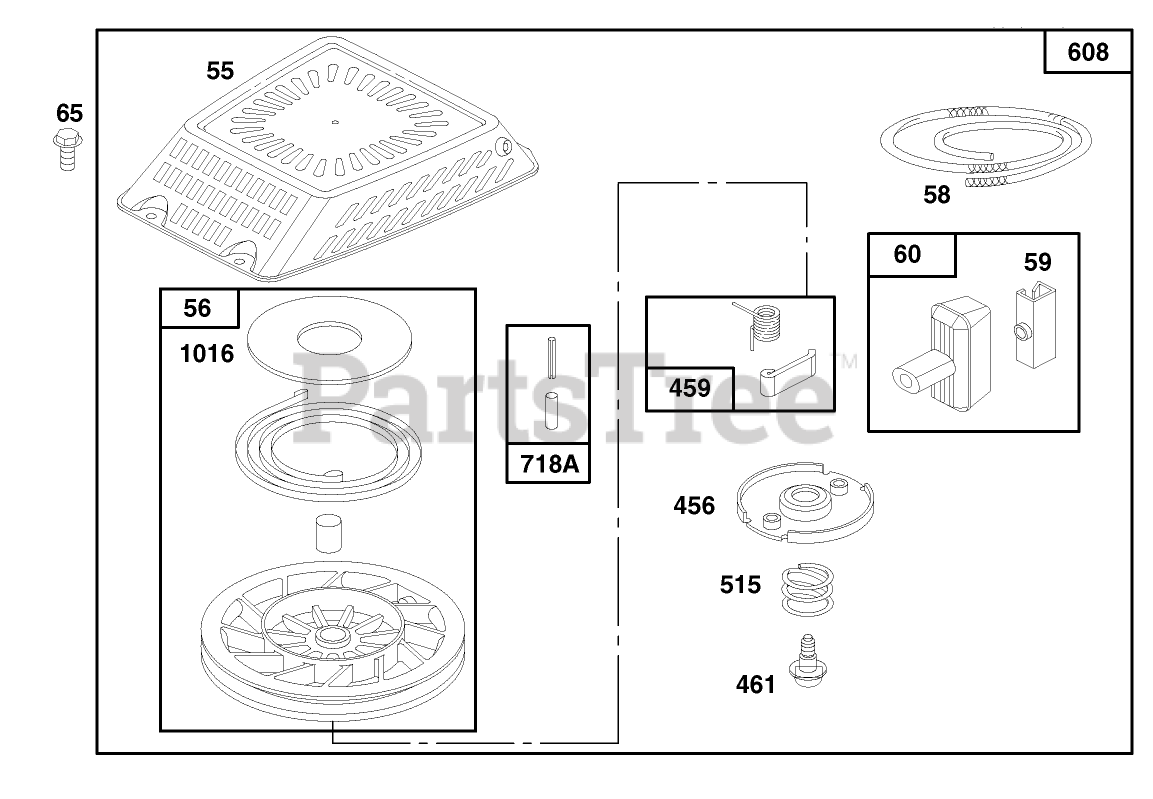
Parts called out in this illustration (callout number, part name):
59	INSERT-HANDLE, REWIND
456	RETAINER - SPRING
515	SPRING - RETAINER
